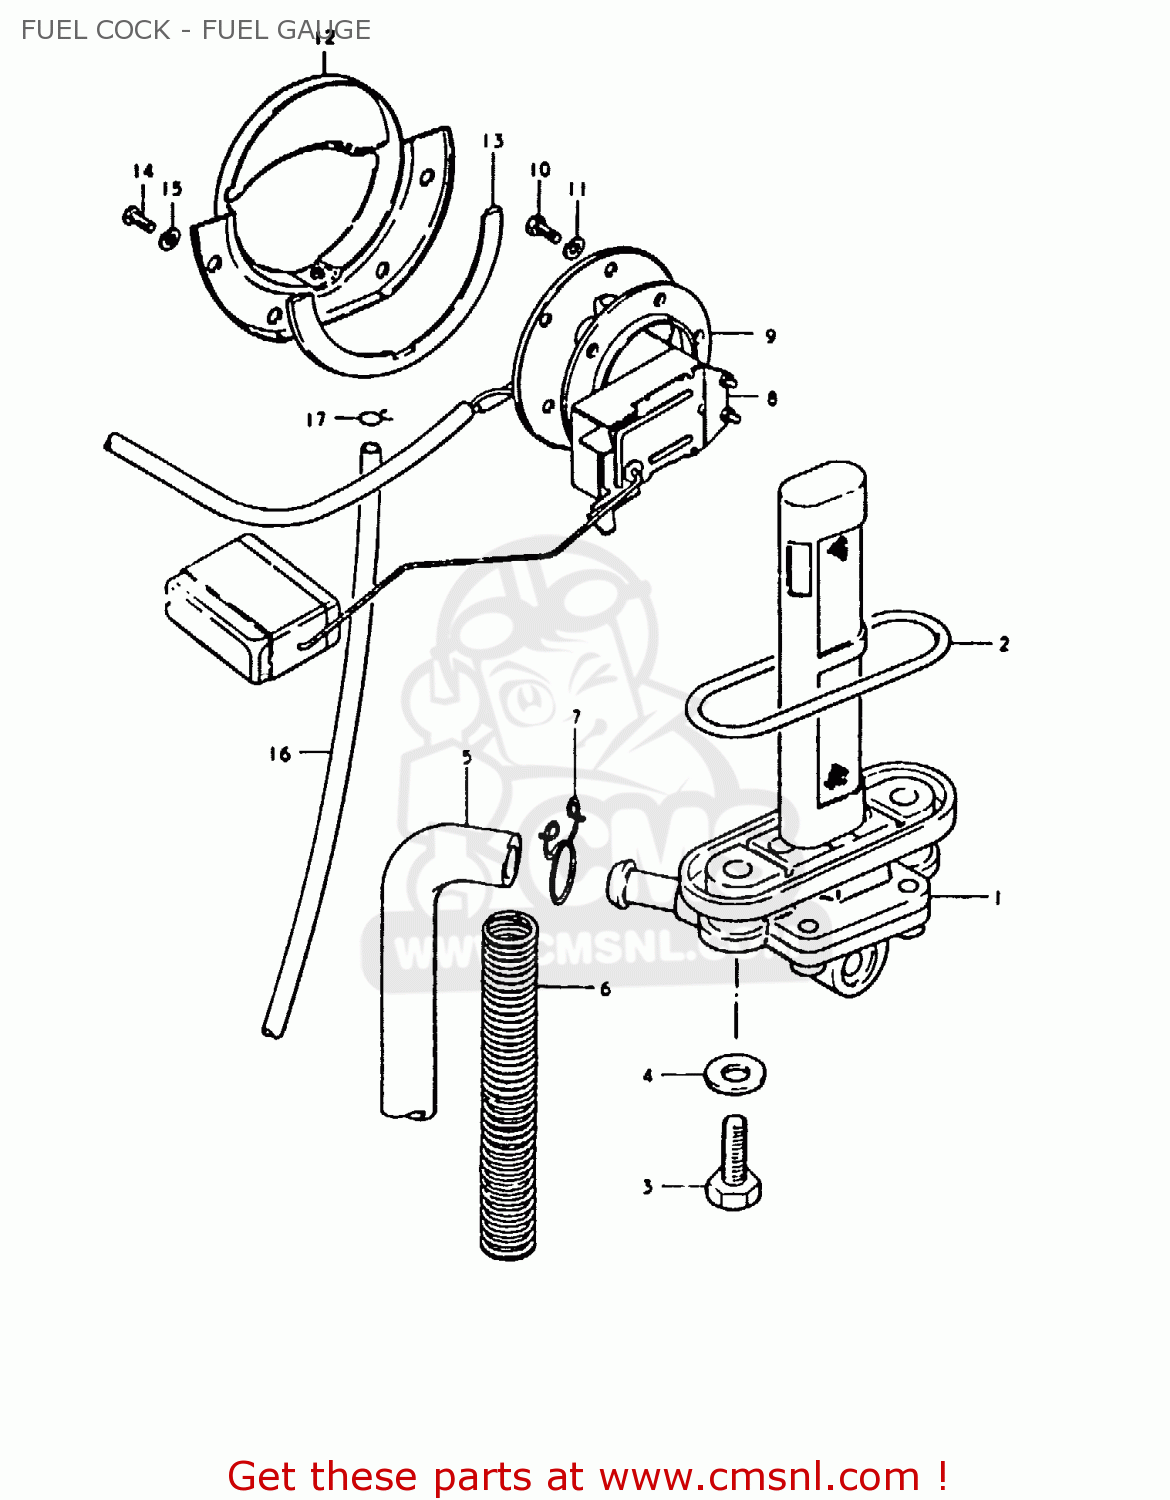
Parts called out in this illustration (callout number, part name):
1	COCK ASSY,FUEL
2	GASKET (NAS)
3	SCREW (6X25)
4	GASKET
5	HOSE
6	SPRING
7	CLIP
8	GAUGE ASSEMBLY,FUEL LEVEL
9	GASKET,FUEL LEVEL GAUGE (NAS)
10	BOLT
11	LOCK WASHER
12	PLATE,FUEL DRAIN
13	GASKET,FUEL DRAIN PLATE (NAS)
14	SCREW
15	LOCK WASHER
16	HOSE,FUEL
17	CLIP
